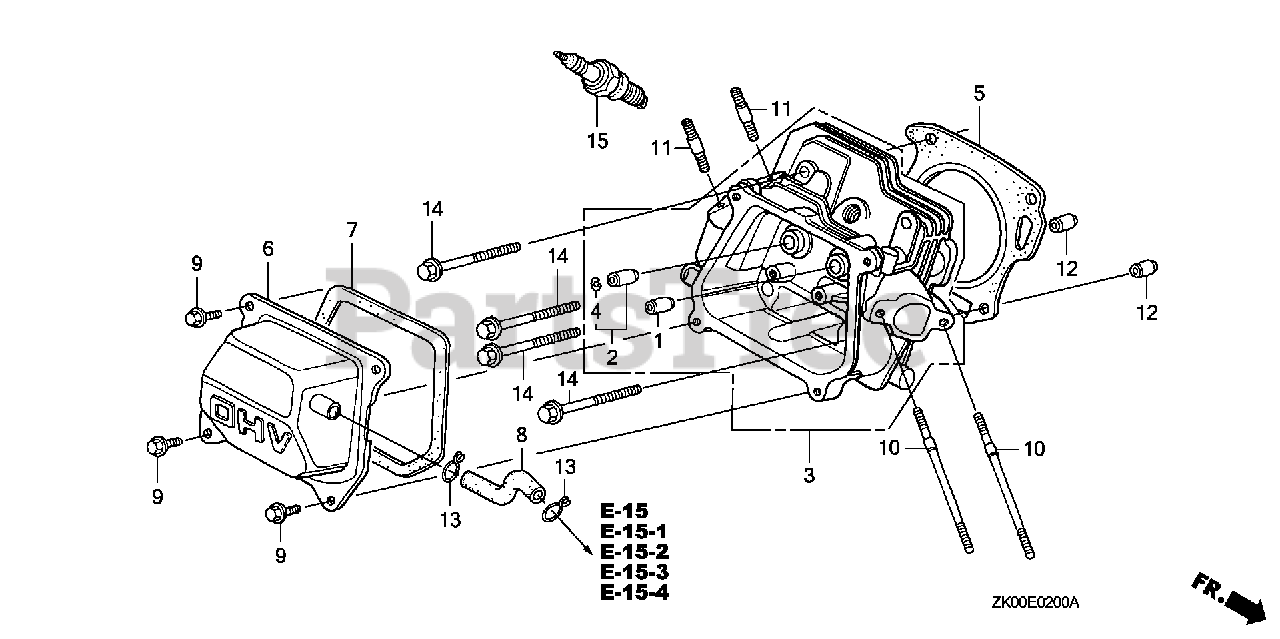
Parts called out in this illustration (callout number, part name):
1	GUIDE, VALVE (OVER SIZE)
2	GUIDE, EX. VALVE (OVER SIZE)
3	CYLINDER HEAD
4	CLIP, VALVE GUIDE
5	GASKET, CYLINDER HEAD (NIPPON LEAKLESS)
6	COVER, HEAD
7	GASKET, HEAD COVER
8	TUBE, BREATHER
9	BOLT, FLANGE (6X12) (CT200)
10	BOLT, STUD (6X112)
11	BOLT, STUD (8X32)
12	PIN, DOWEL (10X16)
14	BOLT, FLANGE (8X60)
15	SPARK PLUG (BPR5ES) (NGK)
15	SPARK PLUG (W16EPR-U) (DENSO)
15	SPARK PLUG (BPR6ES) (NGK)
15	SPARK PLUG (W20EPR-U) (DENSO)
